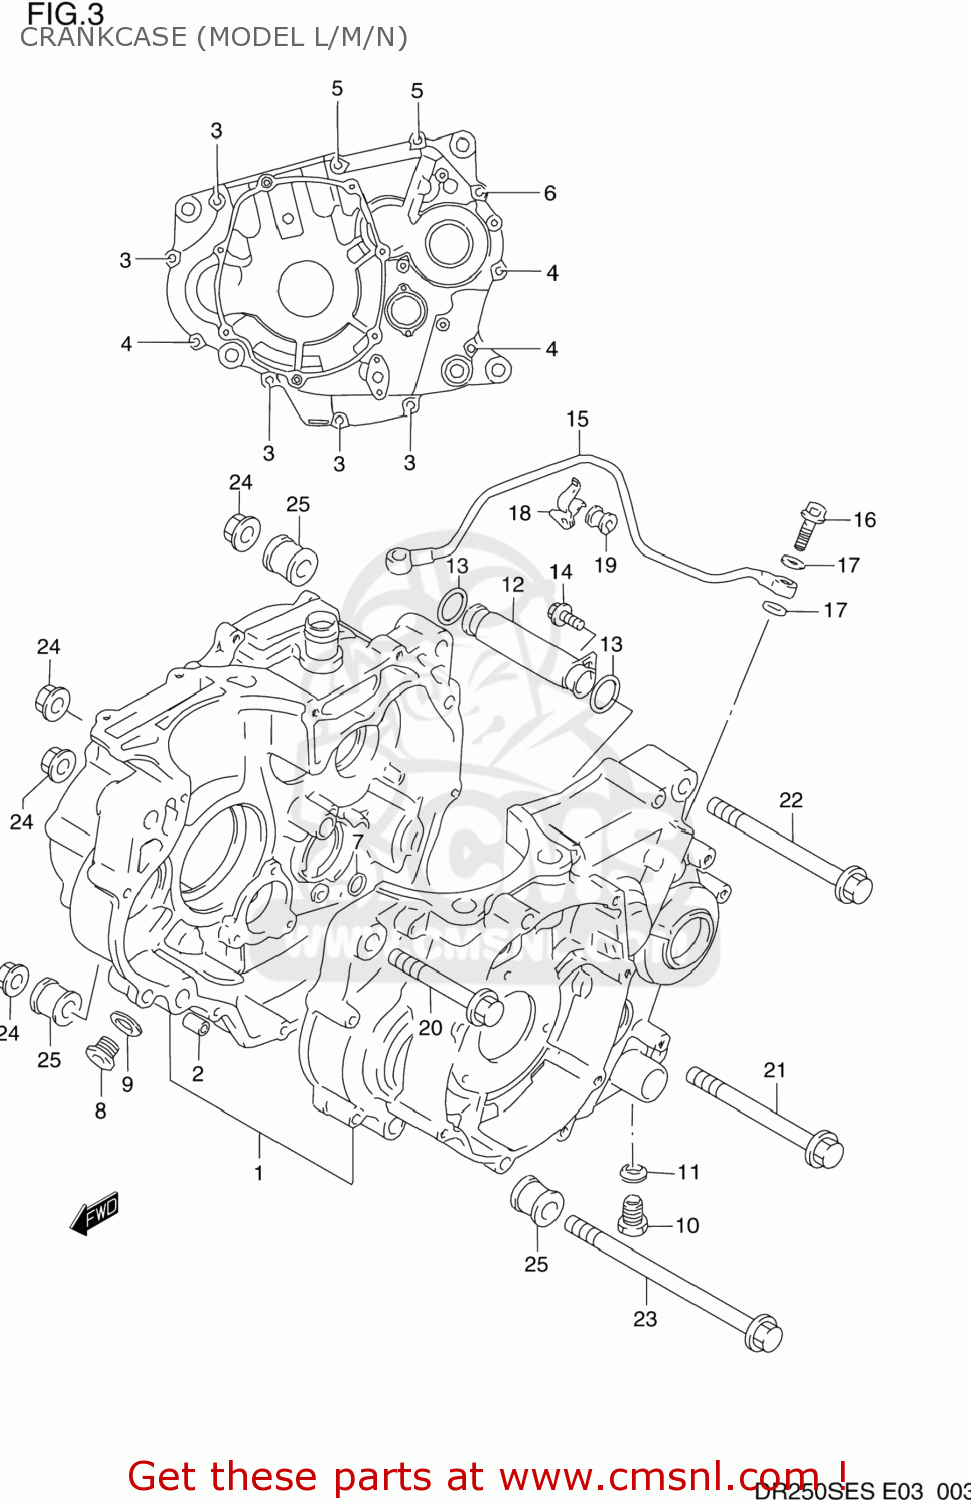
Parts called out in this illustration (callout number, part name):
1	CRANKCASE SET
2	PIN
3	BOLT
4	BOLT
5	BOLT
6	BOLT
7	O-RING
8	PLUG,14X12
9	GASKET(14X19.2X2) (NAS)
10	PLUG,OIL DRN.
11	GASKET(12.1X16.2X3.7) (NAS)
12	PIPE,T/M OIL INNER
13	O RING(D:2.4,ID:15.8)
14	BOLT
15	PIPE,T/M OIL OUTER
16	BOLT UNION
17	GASKET 8.2X14X1 (NAS)
18	CLAMP,OIL PIPE
19	CUSHION
20	BOLT 10X85
21	BOLT(10X101.5)
22	BOLT(10X115)
23	BOLT(10X143)
24	NUT
25	SPACER,ENGINE MOUNT
